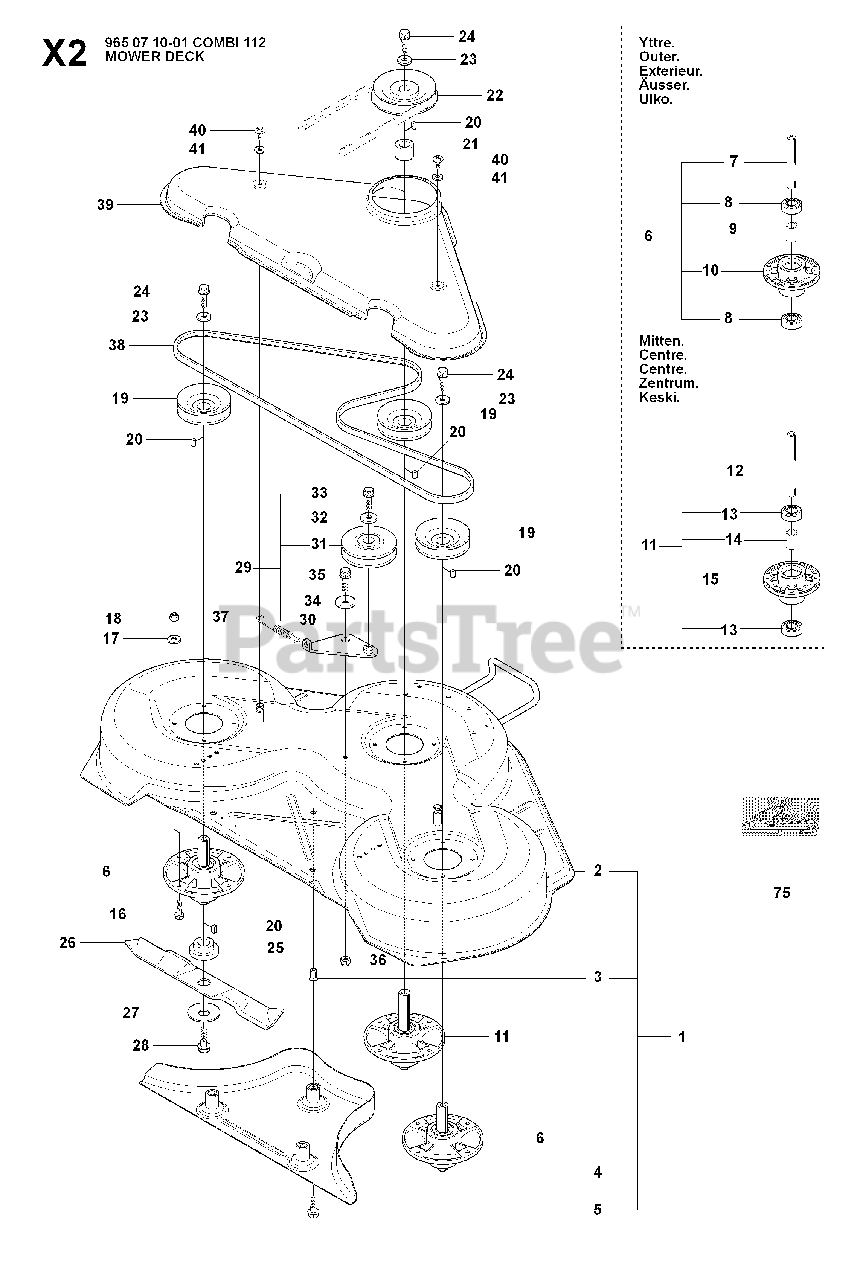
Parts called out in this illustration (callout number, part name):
6	RP SPINDLE ASSY
10	BEARING HOUSING
11	RP SPINDLE ASSY
15	BEARING HOUSING
17	WASHER BRB 8.4X17
18	LOCKNUT M8
26	BLADE
27	WASHER
29	BELT TENSIONER ASSY
30	BELT TENSIONING ARM
34	WASHER
36	LOCKNUT M8
38	BELT
